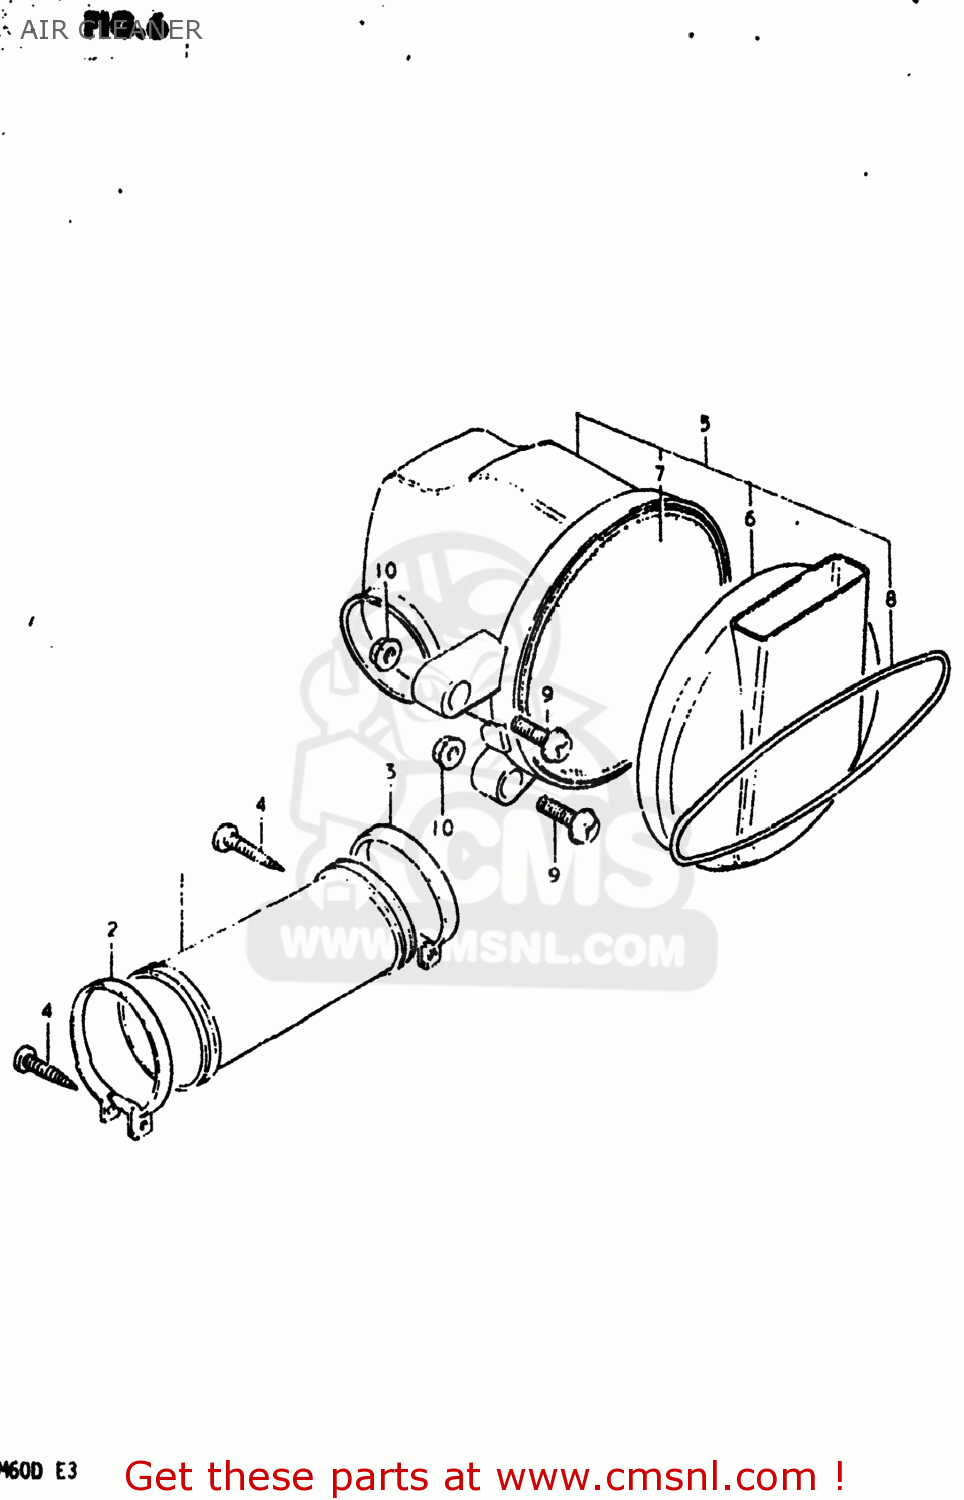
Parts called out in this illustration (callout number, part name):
1	HOSE,CARBURETOR AIR INLET
2	CLAMP
3	CLAMP
4	SCREW TAPP.
5	CLEANER ASSEMBLY,AIR
6	CAP
7	FILTER
8	O-RING,AIR CLEANER
9	SCREW
10	NUT 6MM
